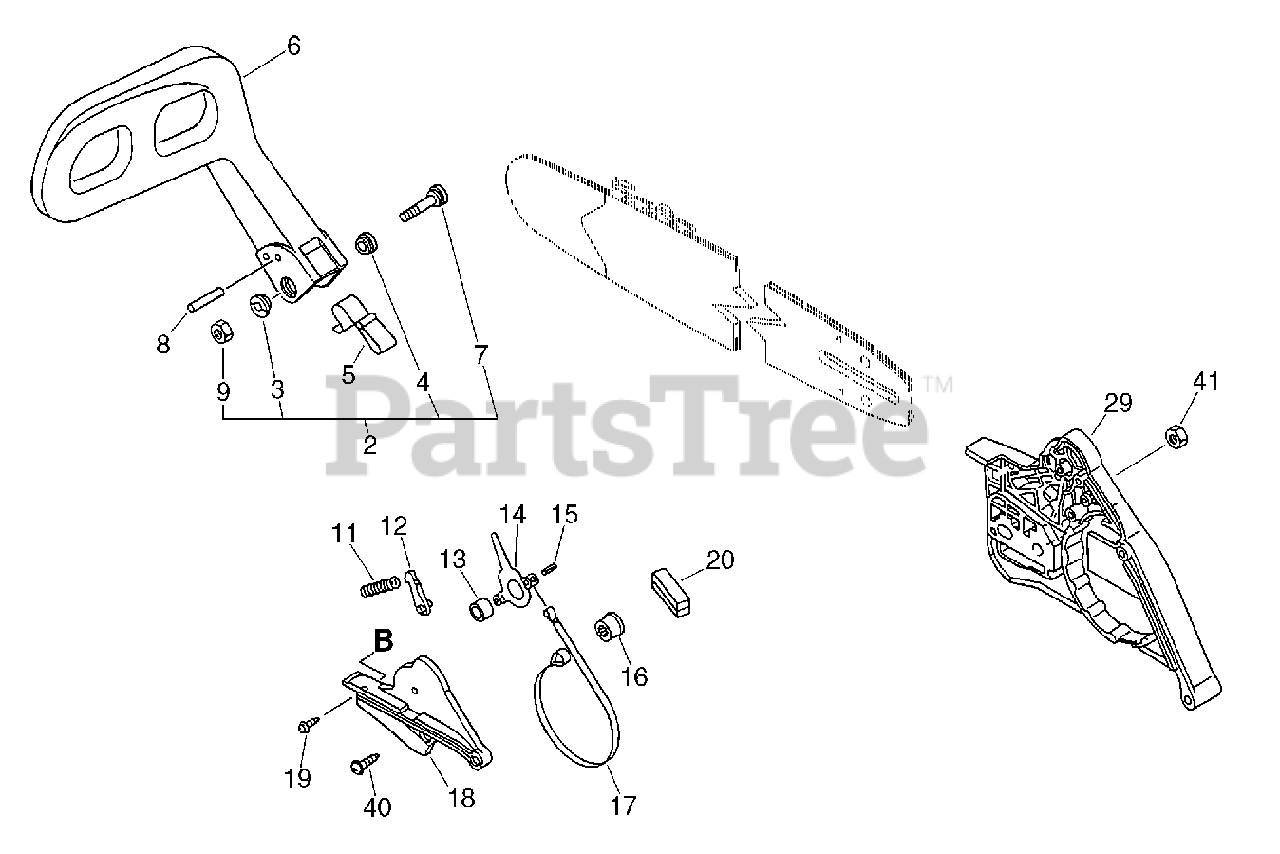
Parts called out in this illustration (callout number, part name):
2	MOUNTING KIT
4	COLLAR - 5
5	SPRING, RETURN
6	LEVER, BRAKE
7	SCREW - 5X35
8	PIN - 3.5X26
9	LOCKNUT - 5
11	SPRING, BRAKE
12	STOPPER, BRAKE
13	SPACER - 8
14	LEVER, BRAKE
15	PIN - SPRING -- 4X8
16	ADJUSTER, BRAKE BAND
17	BAND, BRAKE
18	COVER, BRAKE
19	SCREW - 4X12
29	GUARD, SPROCKET
40	SCREW - 3X18
